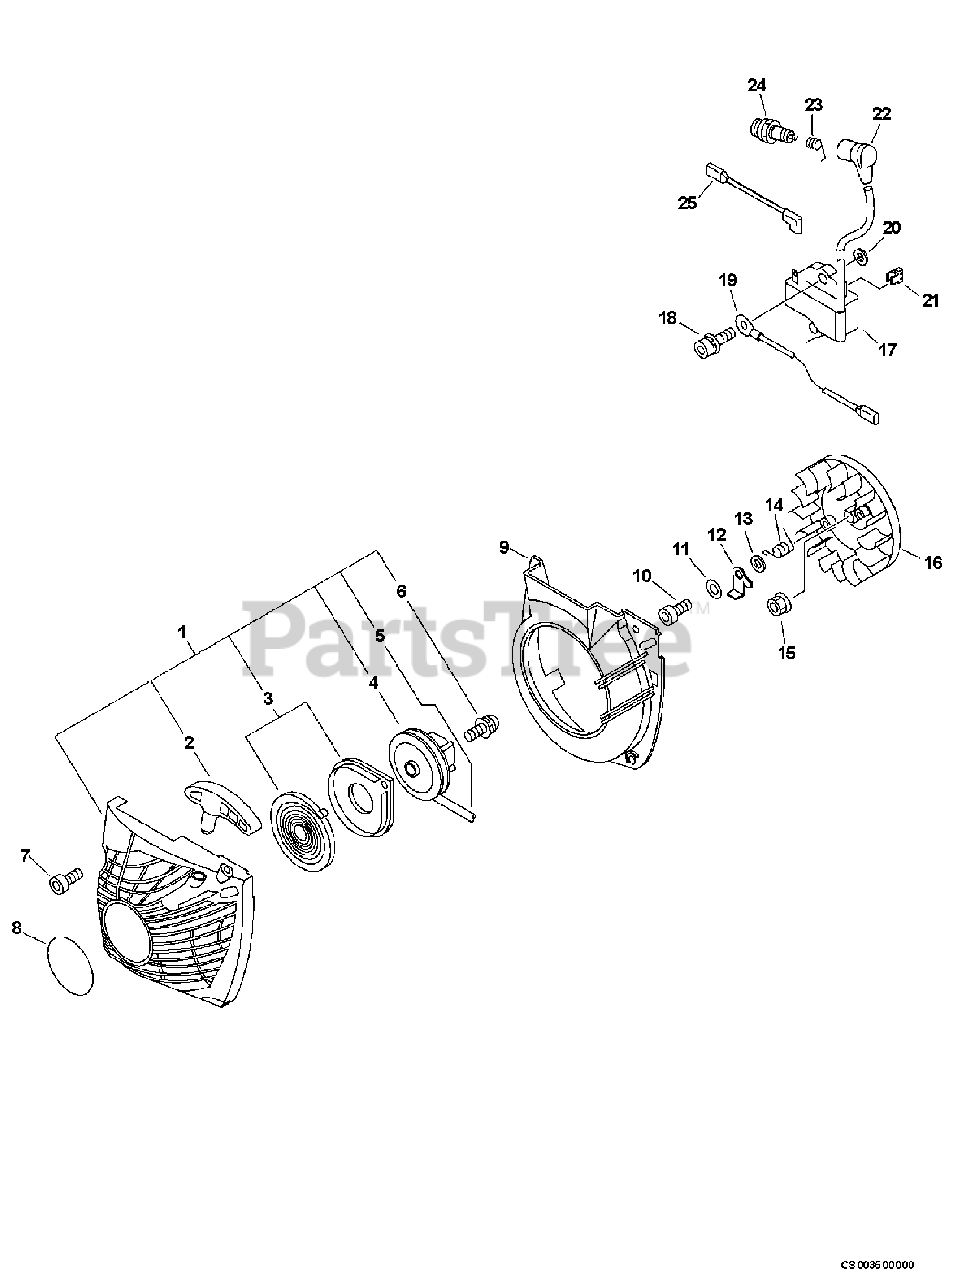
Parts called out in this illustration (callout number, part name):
1	STARTER ASSY
2	GRIP, STARTER
3	REWIND SPRING ASSY
4	REEL, ROPE
5	ROPE, STARTER - 3.5X900
6	SCREW
7	SCREW - 5X20 -- TAPPING
8	LABEL - ECHO
9	COVER, FAN
10	SCREW - 5X14
11	WASHER - 5
12	PAWL, STARTER
14	SPRING, RETURN
15	NUT - 8 -- FLANGE
16	FLYWHEEL
17	COIL, IGNITION
18	SCREW - 5X20
19	LEAD - GROUND
22	CAP, SPARK PLUG
23	TERMINAL, SPARK PLUG CAP
24	SPARK PLUG -- BPM-8Y
24	SPARK PLUG -- BPMR-8Y
25	LEAD - IGNITION
